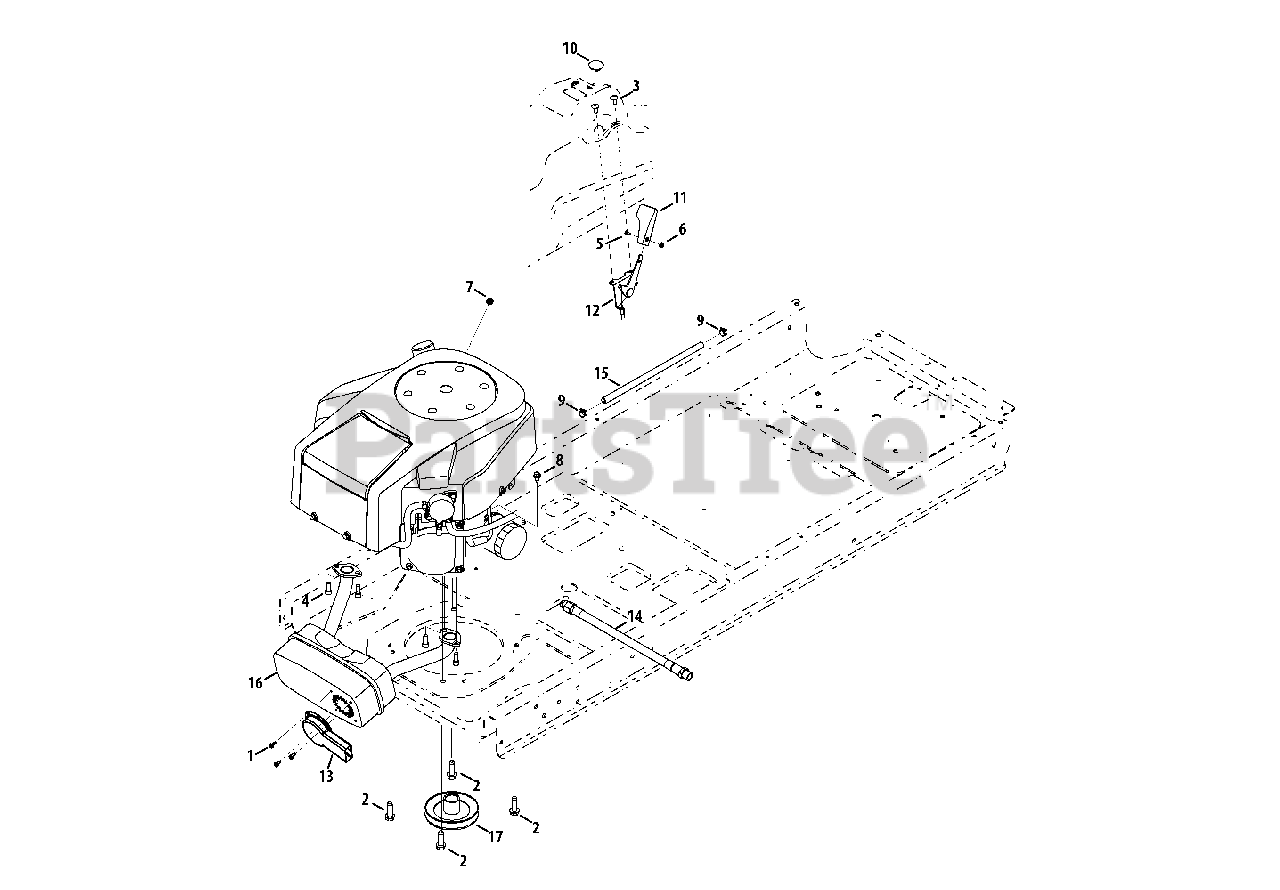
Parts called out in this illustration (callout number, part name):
1	Hex Washer Screw, #8-18 x .500
2	Hex Washer Screw, 3/8-16 x 1.00
3	Screw, 1/4-20 x .50
4	Socket Head Screw, 5/16-18 x .750
5	Screw, #8-32 x .375
6	Hex Nut, #8-32
7	Flange Lock Nut, 1/4-20
8	Hex Washer Screw, 1/4-20 x .625
9	Hose Clamp, .490 Dia.
10	Choke Plug
11	Throttle Control Knob
12	Throttle/Choke Control Cable
13	Muffler Deflector
14	Oil Drain Hose
15	Fuel Hose, 1/4
16	Twin Muffler
17	Engine Pulley
